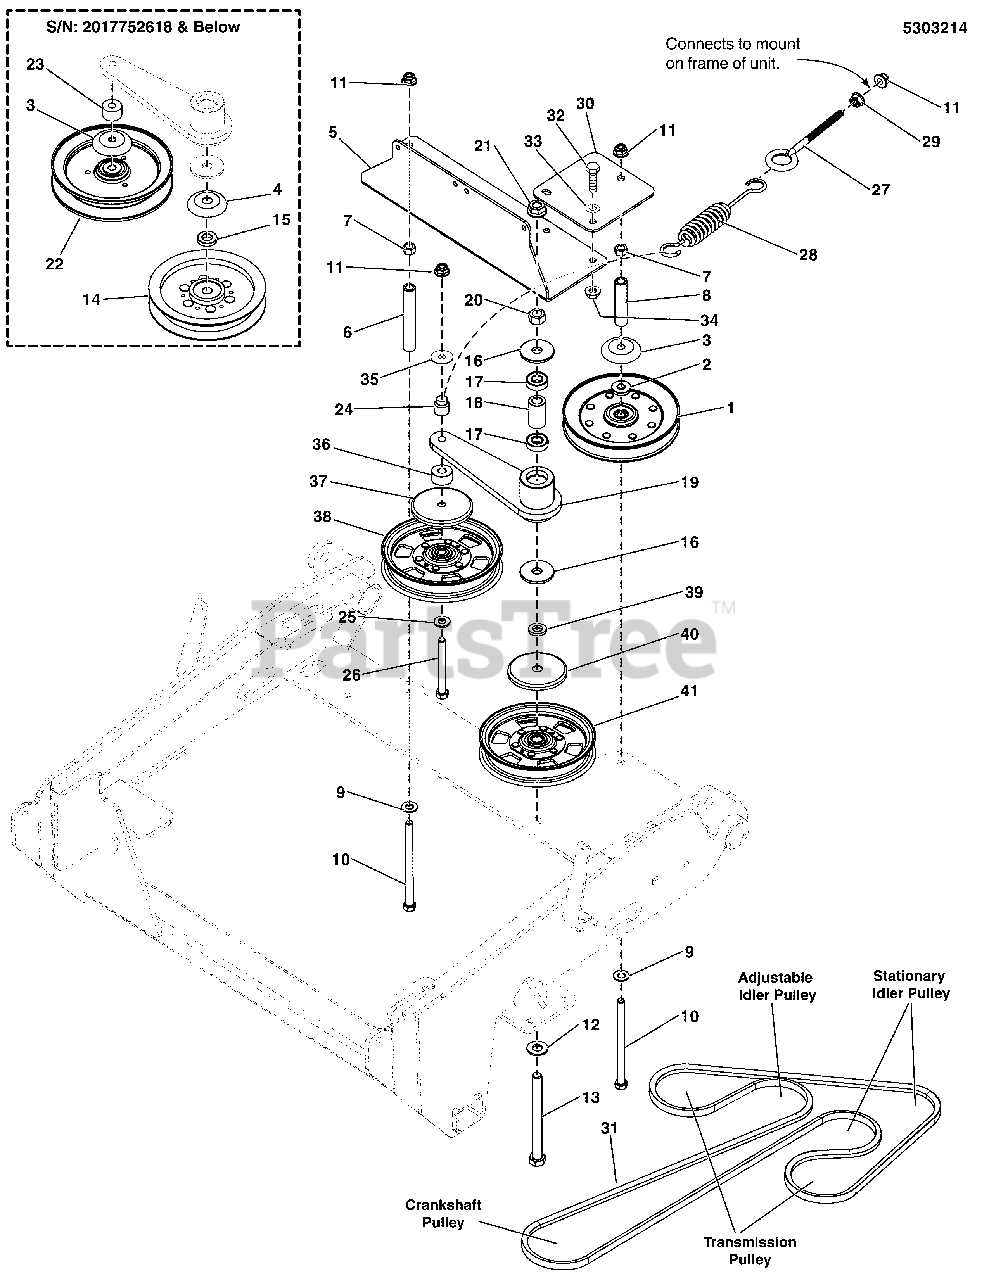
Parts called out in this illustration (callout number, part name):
1	PULLEY, IDLER-V, 5.83OB, .381ID, .94W
2	SPACER, .390 X 1.00 X .188, CZ
3	SHIELD, BEARING PULLEY, 3/8ID
4	SHIELD, PULLEY BEARING
5	PLATE, RESERVOIR MOUNT - BLK
6	SPACER, .39 X .63 X 4.06, CZ
7	NUT, 3/8-16 HEX
8	SPACER, .39 X .63 X 2.81, CZ
9	WASHER, 3/8 SAE
10	BOLT, 3/8-16 X 5-1/2 GD5 YZ
11	NUT, 3/8-16 HEX NYLOCK FLANGE
12	WASHER, 1/2 SAE
13	BOLT, 1/2-13 X 5-1/2 GD5 YZ
14	PULLEY, IDLER 5"OD .500ID, .75W STL
15	SPACER, .52 X 1.00 X .22, CZ
16	SPACER, IDLER ARM, 1/2"
17	BEARING, BALL, AXLE
18	SPACER, .52 X .84 X 1.53, PM
19	WELD, ARM, PUMP DRIVE IDLER, 6.38 - BLK
20	NUT, 1/2-13 HEX, YZ
21	NUT, 1/2-13 HEX NYLOCK FLANGE
22	PULLEY, C-SEC, V-IDLER, 6.25"ODX3/8ID
23	SPACER, .39 X 1.00 X .63, CZ
24	SPACER, SHOULDER
25	WASHER, 3/8 GD.9 FLAT
26	BOLT, 3/8-16 X 3-1/2 GD5 CZ
27	EYE BOLT, 3/8-16 X 6, 3.0 THREAD
28	SPRING-EXT, 1.25OD X 9.3LG X .142WR, BLK
29	NUT, 3/8-16 HEX SERRATED FLANGE
30	PLATE, PULLEY SUPPORT - BLK
31	BELT, A-SEC, 114.3"EL, ARAMID, WRPD
32	BOLT, 5/16-18 X 3/4 GD5
33	WASHER, 5/16 SAE
34	NUT, 5/16-18 HEX NYLOCK FLANGE
35	WASHER-3/8 FENDER
36	SPACER, .39 X 1.00 X .50, PM, CZ
37	SHIELD, BEARING, 3/8ID X 2-7/8OD, CZ
38	PULLEY, FLT IDLER, 5.0 X .75 X .38, CZ
39	SPACER, .52 X .88 X .14, BZ
40	SHIELD, BEARING, 1/2ID X 2-7/8 OD, CZ
41	PULLEY, FLT IDLER, 5.0 X .75 X .50SH, CZ
